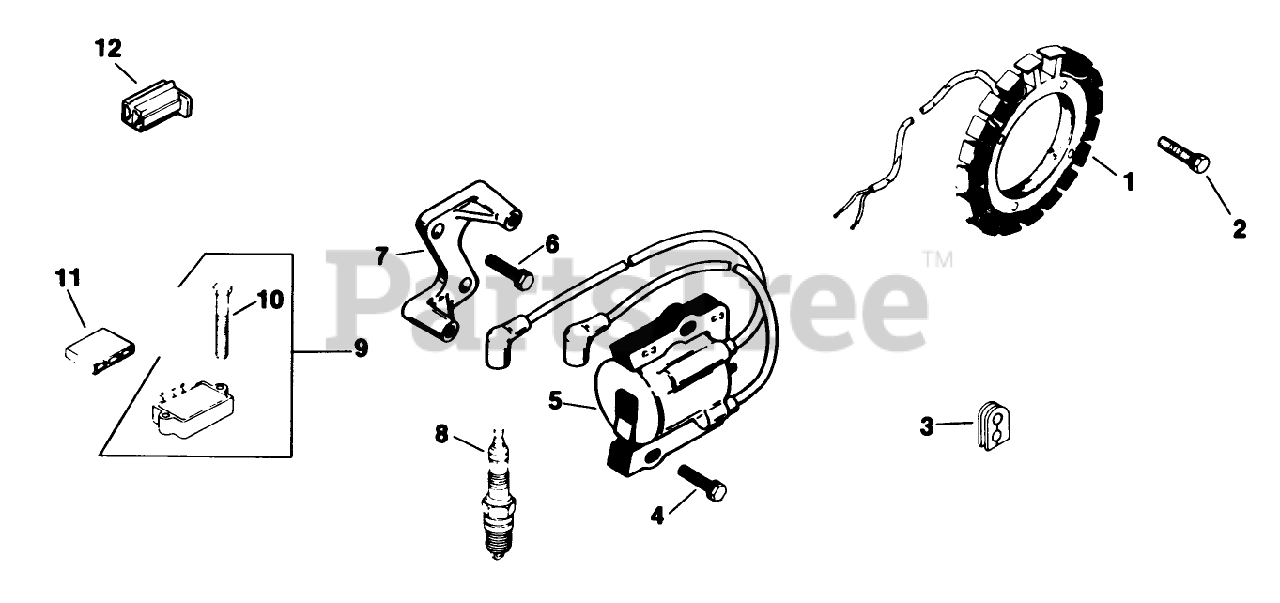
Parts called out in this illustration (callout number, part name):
1	Stator
2	Screw
3	Grommet
4	Screw-Hex Washer Hd.
5	Module-Ignition
6	Screw-Hex Washer Hd.
7	Bracket-Module
8	Plug-Spark
9	Kit-Rectifier-Regulator (Incl. Ref. #10)
10	Screw
11	Connector
12	Connector
